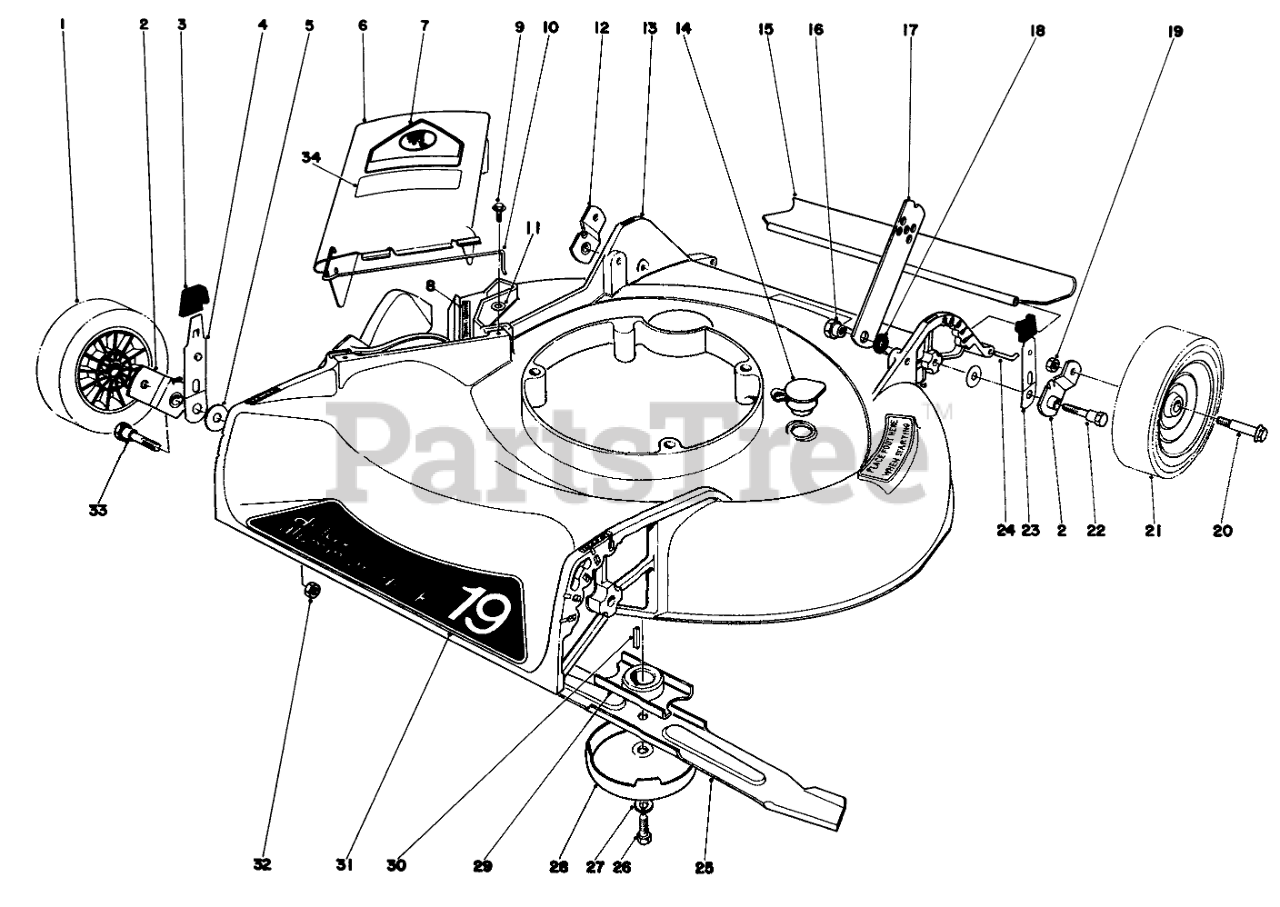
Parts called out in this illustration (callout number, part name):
1	Wheel Assembly
2	Pivot Arm
3	KNOB-ARM
4	SPRING ARM ASM
5	Pivot Washer
6	Deflector-Cover Assembly (Incl. Ref. #7-10 & 34)
7	DECAL-DANGER
8	Decal
9	SCREW
10	SPRING HINGE
11	WASHER-FLAT
12	Pivot Arm
13	Housing
14	WASHOUT PLUG
15	SHIELD - TRAILING
16	HANDLE PIVOT NUT
17	Handle Latch
18	HANDLE LATCH SPACER
19	Nut
21	Wheel & Tire Assembly
22	PIVOT SCREW
23	SPRING ARM ASM
24	SHIELD ROD
25	Blade
26	SPECIAL SCREW
27	WASHER-LOCK
28	AntiScalp Cup
29	Blade Retailer
30	KEY-SQUARE
31	Decal
32	Nut
33	PIVOT SCREW
34	Decal-Caution
